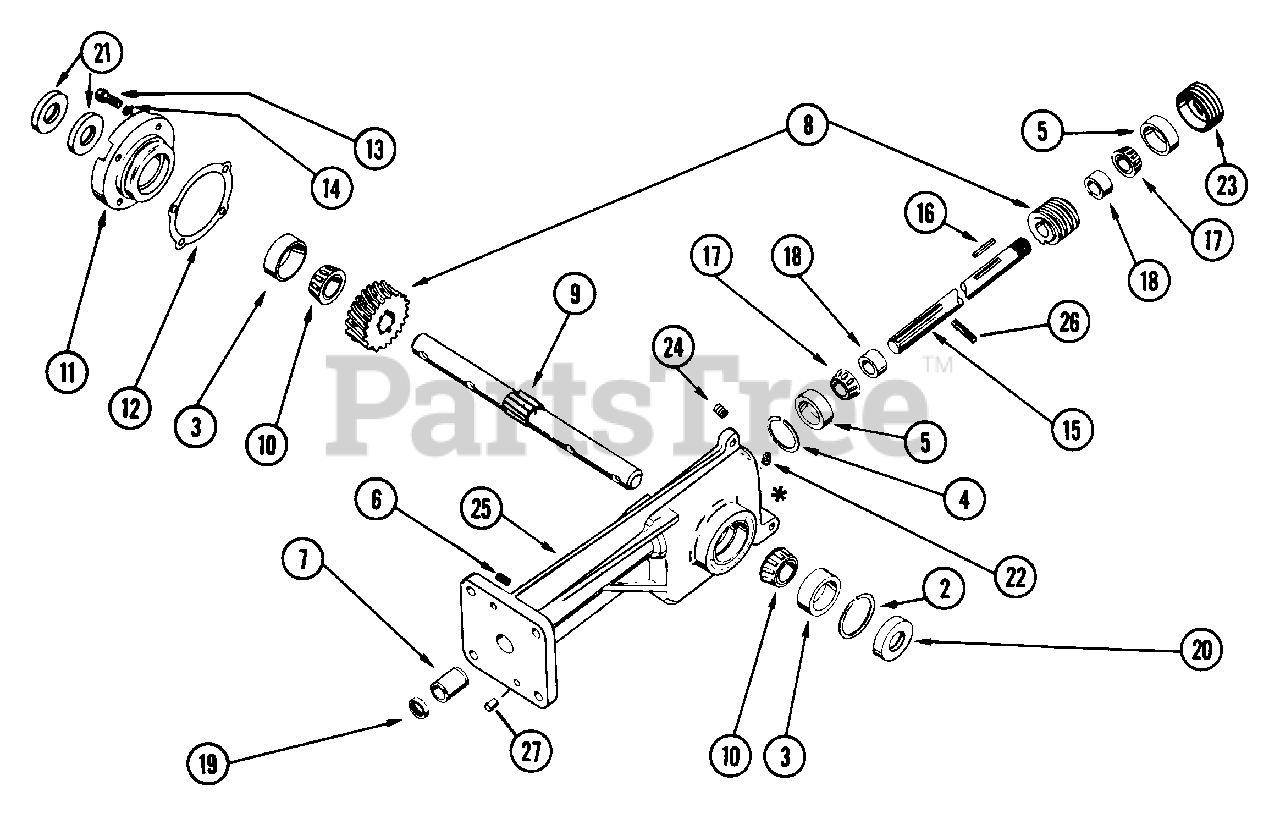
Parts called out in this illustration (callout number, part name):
1	TILLER GEARCASE ASSEMBLY
2	RG-RTNG-INT 1.969X.062
3	BRG-CUP1.980X.420
4	RG-RTNG-INT 1.781X.062
5	BRG-CUP 1.781X.475
6	BREATHER
7	BRG-NEEDLE .750X1.0X.62
8	WORM & WORM GEAR SERVICE ASSY
9	TINE SHAFT
10	BRG-CONE 1.0X.58
11	BEARING FLANGE
12	SERVICE KIT
13	BLT-HEX .38-16X1.00 PL GR5
14	WSHR-LK .375X.115 HVY PL
15	WORM SHAFT
16	KEY-SQ .188X1.0X.188 SAE 8630
17	BRG-CONE .750X.61
18	BSHG, SPCR .755X1.12X.50 PM
19	SEAL .750X1.000X.125
20	SEAL 1.000X1.980X.375
21	SEAL 1.000X1.785X.250
22	PIPE PLUG
23	ADJUSTMENT PLUG
24	SCR-SET .25-20X.25 SKHCUPNY OH
25	TILLER GEARCASE - C.I.
26	PIN-ROLL .125X1.00
27	PIN-GRV .375X1.00 TP C
